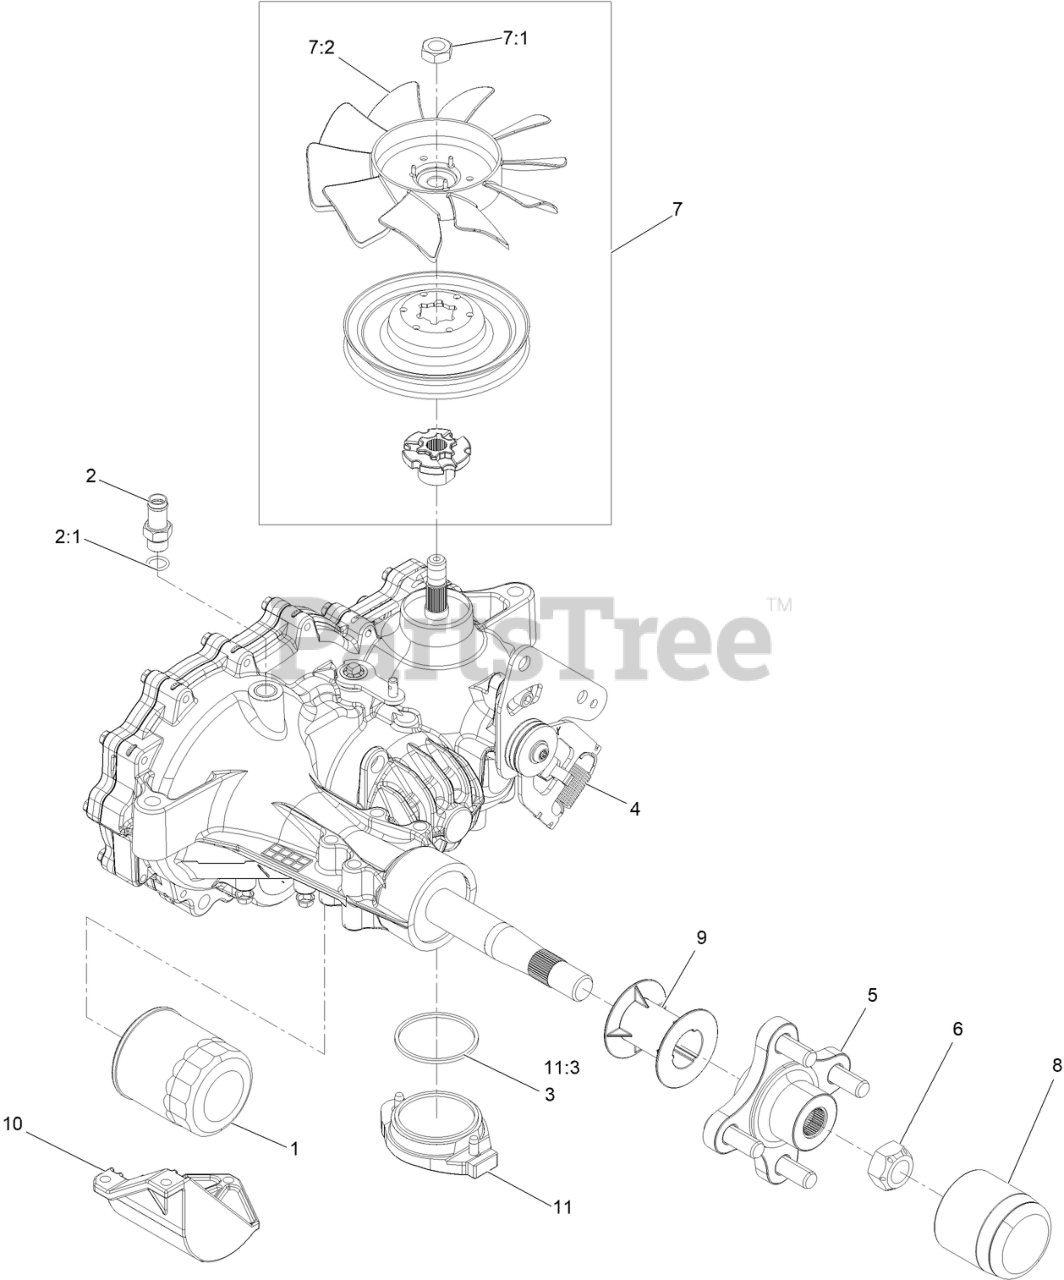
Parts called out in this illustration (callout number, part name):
1	ELEMENT-OIL FILTER, HYD
2	ADAPTER-STRAIGHT
2:1	O-RING
3	O RING-SEAL
4	SPRING-EXTENSION
5	HUB-OFFSET
6	NUT-HUB
7	FAN AND PULLEY KIT
7:1	NUT-HJ
8	CAP-AXLE, LONG
9	TUBE-AXLE
10	GUARD-FILTER, RH
11	CHARGE KIT
11:3	O RING-SEAL
99	BRAKE SHAFT SEAL KIT
